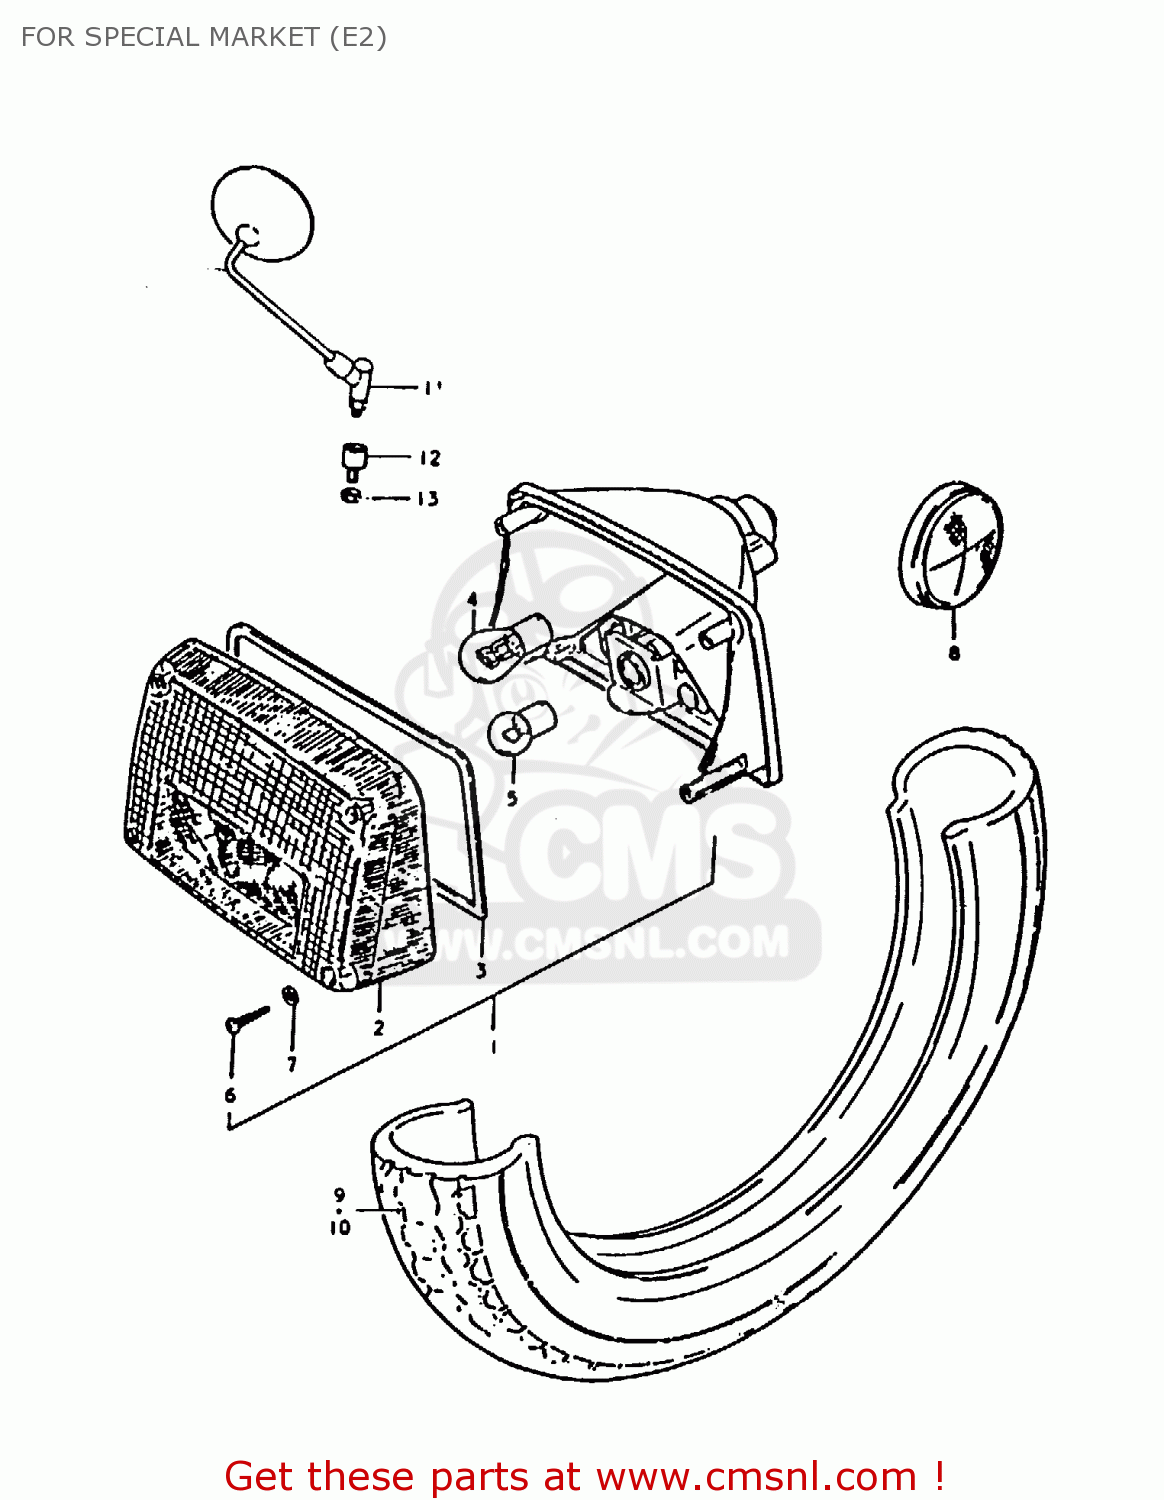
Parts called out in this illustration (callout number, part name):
1	LAMP ASSY, REAR COMBINATION
2	LENS
3	GASKET (NAS)
4	BULB 12V21/5W
5	BULB
6	SCREW
7	GASKET (NAS)
8	REFLEX REFLECTOR,RR
9	TIRE,FRONT
10	TIRE, REAR
11	MIRROR ASSY,RH
12	CUSHION,REAR VIEW MIRROR
13	NUT
